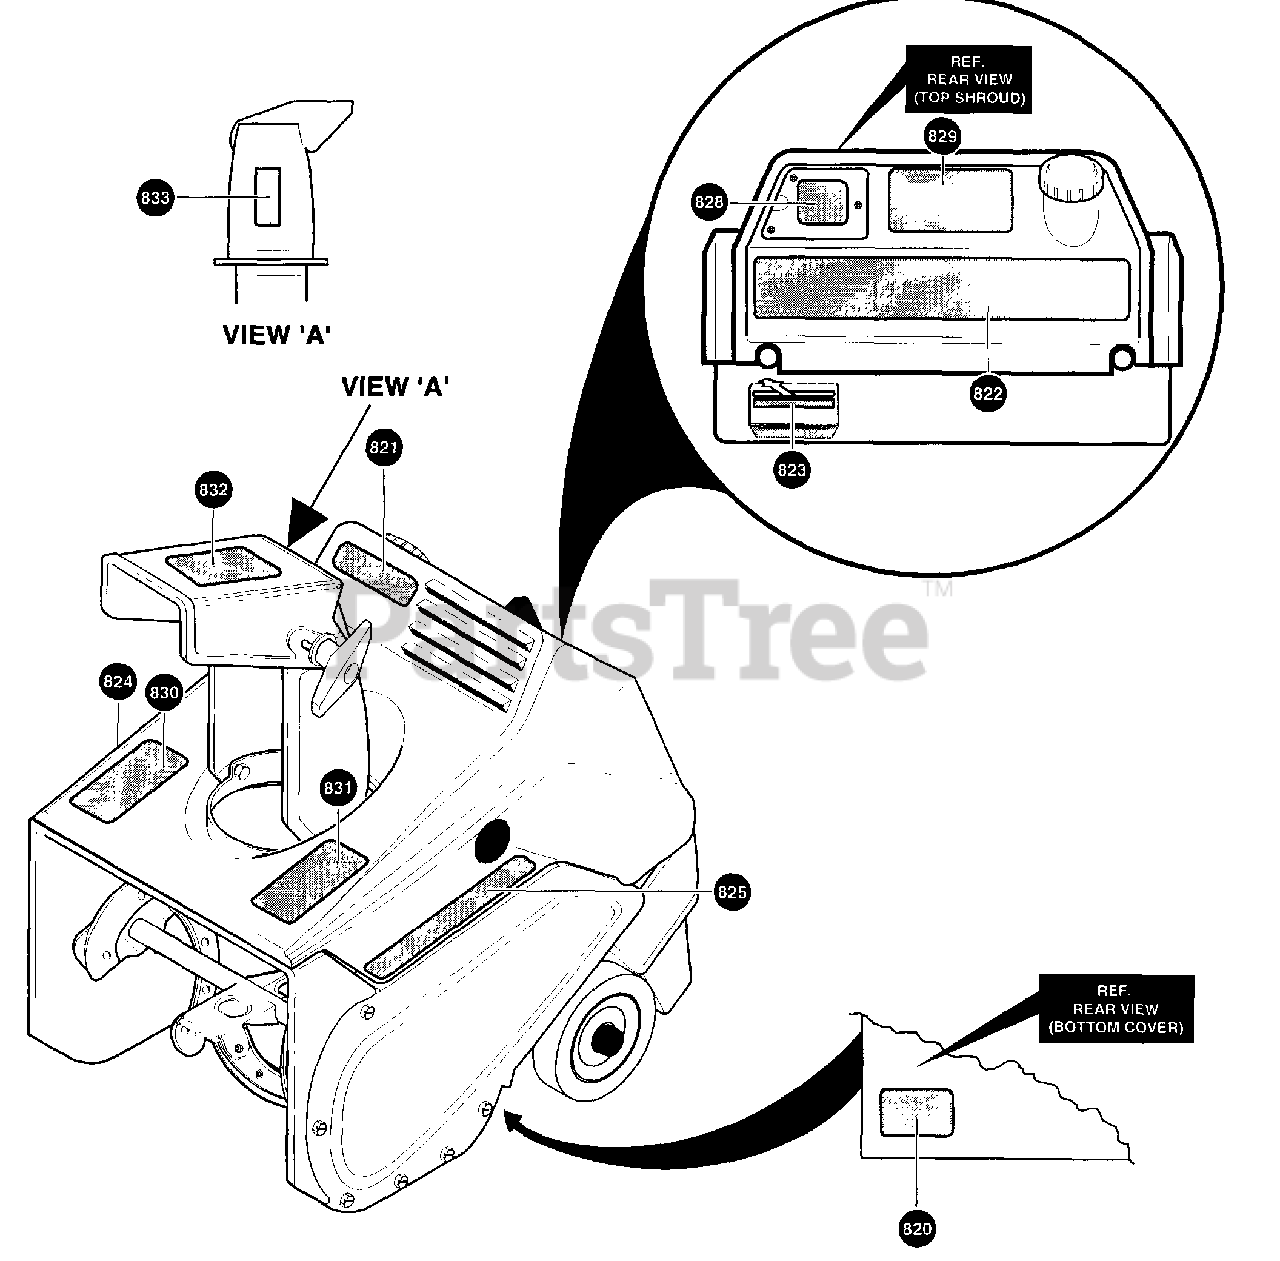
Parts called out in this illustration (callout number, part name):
821	DECAL, HUSQVARNA
822	DECAL, CONTROL PANEL
823	DECAL, OFF-CHOKE-ON
824	DECAL, RH SHROUD SIDE
825	DECAL, LH SHROUD SIDE
828	DECAL, FUEL MIX
829	DECAL, START INSTRUCTIONS
830	DECAL, DANGER CHUTE ENG/FR
831	DECAL, DANGER AUGER ENG/FR
832	DECAL, HUSQVARNA CROWN
833	DECAL, SAFETY INSTRUCTIONS
